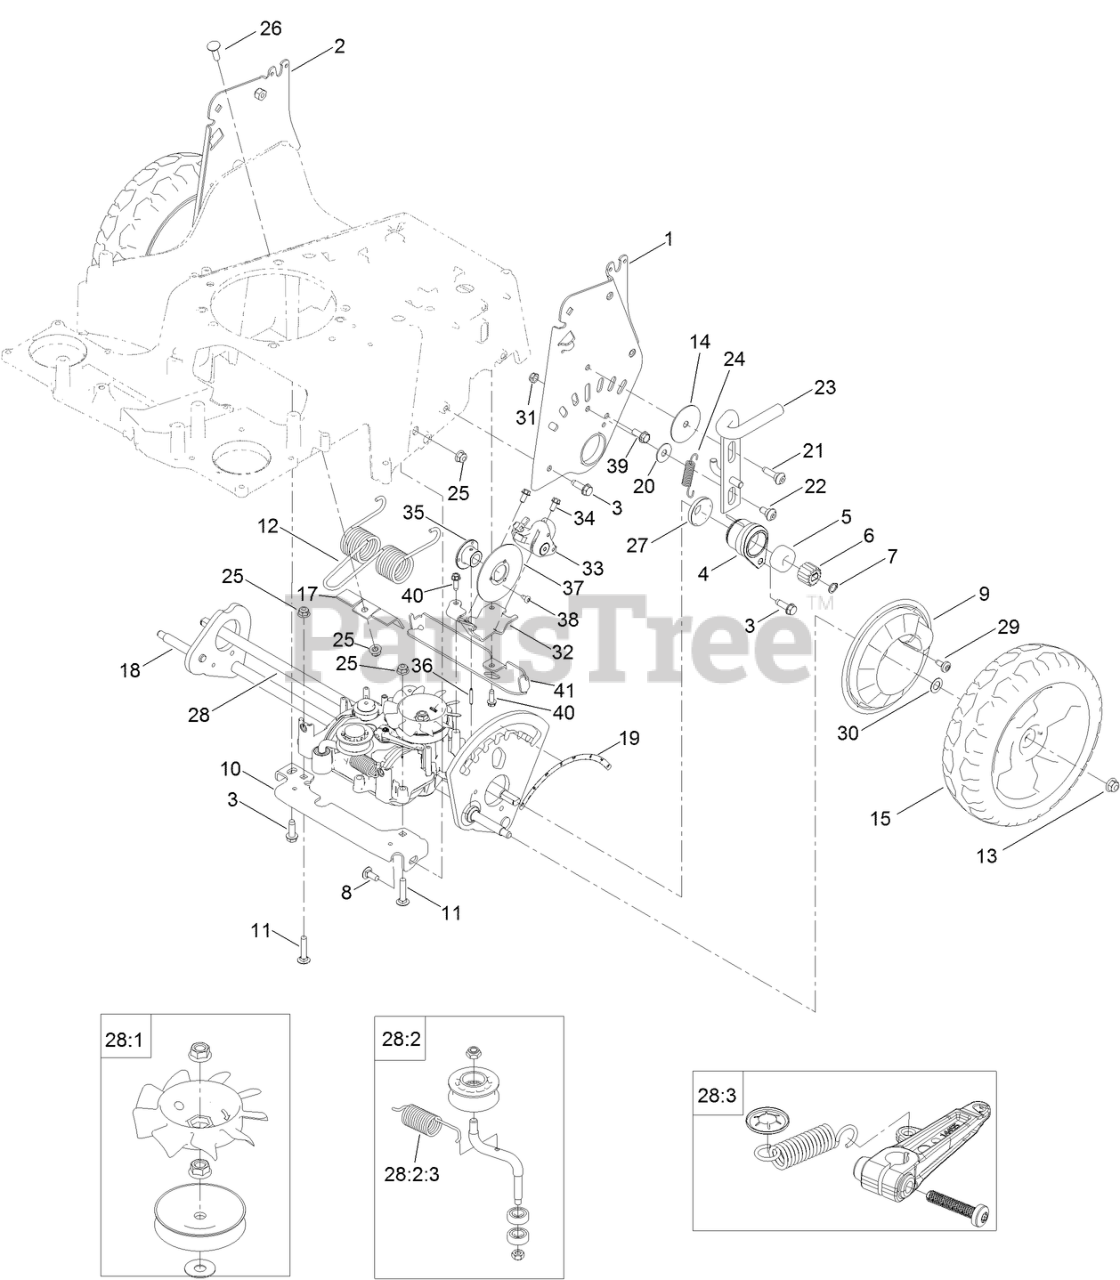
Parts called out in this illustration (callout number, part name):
1	HOC PLATE ASSEMBLY
2	HOC PLATE ASSEMBLY
3	SCREW-THD ROLL, HWH
4	BEARING RETAINER ASM
5	BEARING-BALL, CUSTOM
6	GEAR-PINION, 15T
7	RING-RETAINING
8	SCREW-CARR
9	COVER-WHEEL
10	BRACKET-TRANSMISSION, FRONT
11	BOLT-CARR
12	SPRING-TORSION
13	NUT-HF, NI
14	WASHER-PLAIN
15	10.5 IN. WHEEL ASM
17	BRACKET
18	REAR AXLE ASM
19	DECAL-HOC, REAR
20	WASHER
21	SCREW-SHOULDER, BHTF
22	BOLT-SHOULDER
23	LOCK-HEIGHT, ADJ
24	SPRING-EXTENSION
25	NUT-HF, NI
26	BOLT-CARR
27	COVER-BEARING
28	TRANSMISSION-MV702
28:1	PULLEY FAN REPAIR KIT
28:2	IDLER PULLEY REPAIR KIT
28:2:3	SPRING-TENSION, BELT
28:3	CLUTCH LEVER REPAIR KIT
29	SCREW-SHOULDER
30	WASHER-PLAIN
31	NUT-LOCK, NI
32	BRACKET-MOUNT, BRAKE
33	CALIPER-BRAKE, DISC
34	SCREW-HWH
35	HUB-ROTOR
36	PIN-ROLL
37	DISC-ROTOR
38	SCREW-TORX PH THD ROLL
39	SCREW
40	SCREW-HWHTF
41	BRACKET-SUPPORT, CABLE
